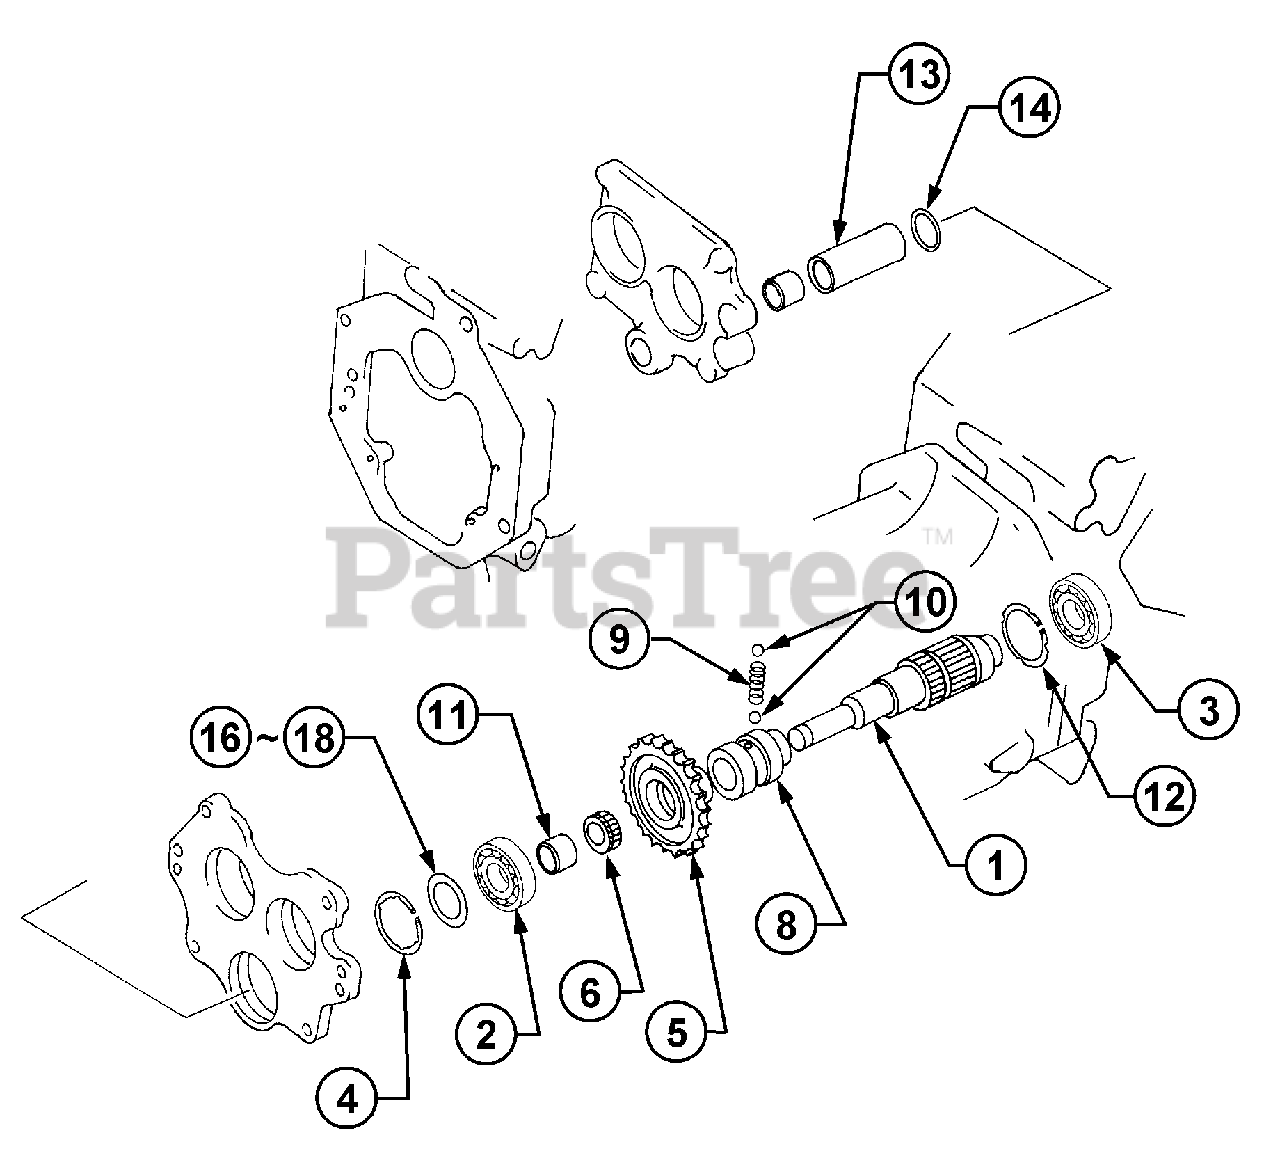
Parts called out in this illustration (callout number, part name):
2	Bearing, Ball
3	Bearing, Ball
6	Bearing, Needle
16	Liner, t=0.15
